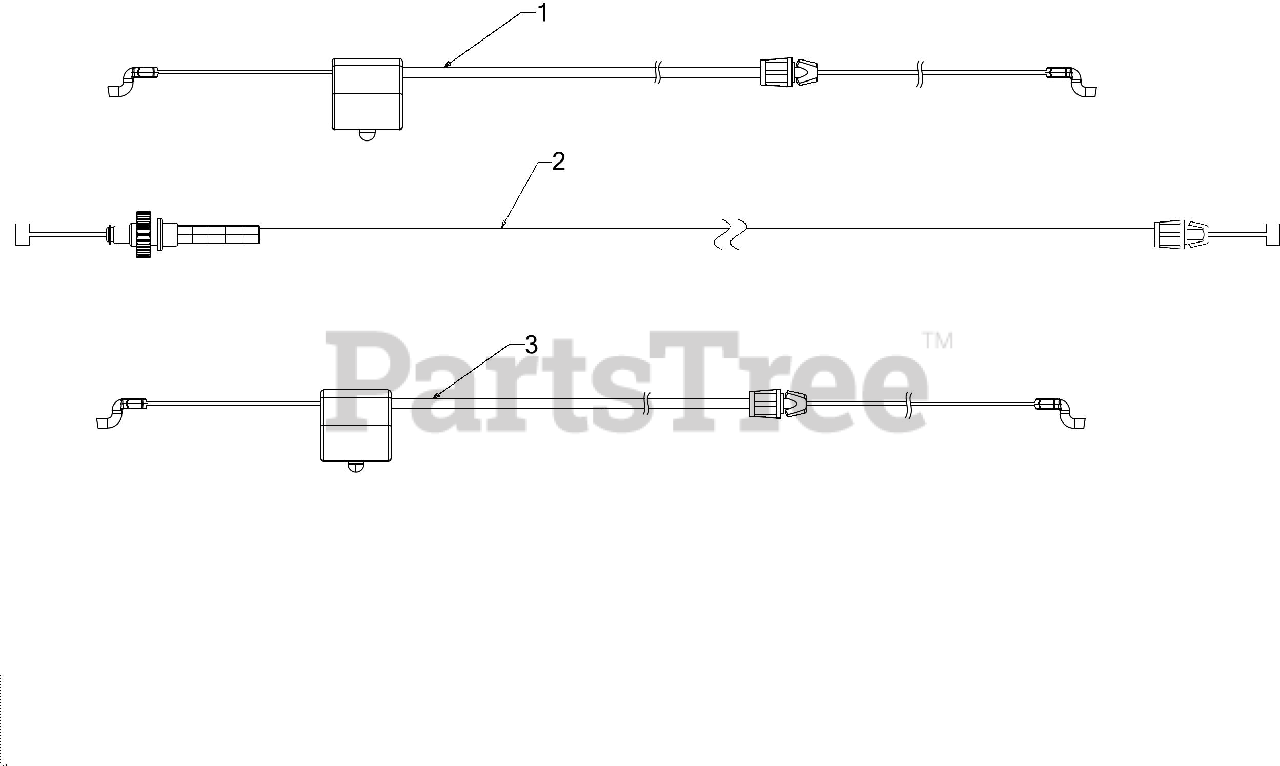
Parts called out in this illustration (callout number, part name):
1	SPEED SELECT CABLE W/ELBOW
2	SPEED ADJUSTMENT CABLE 56.25"
3	CONTROL CABLE 37.58"
